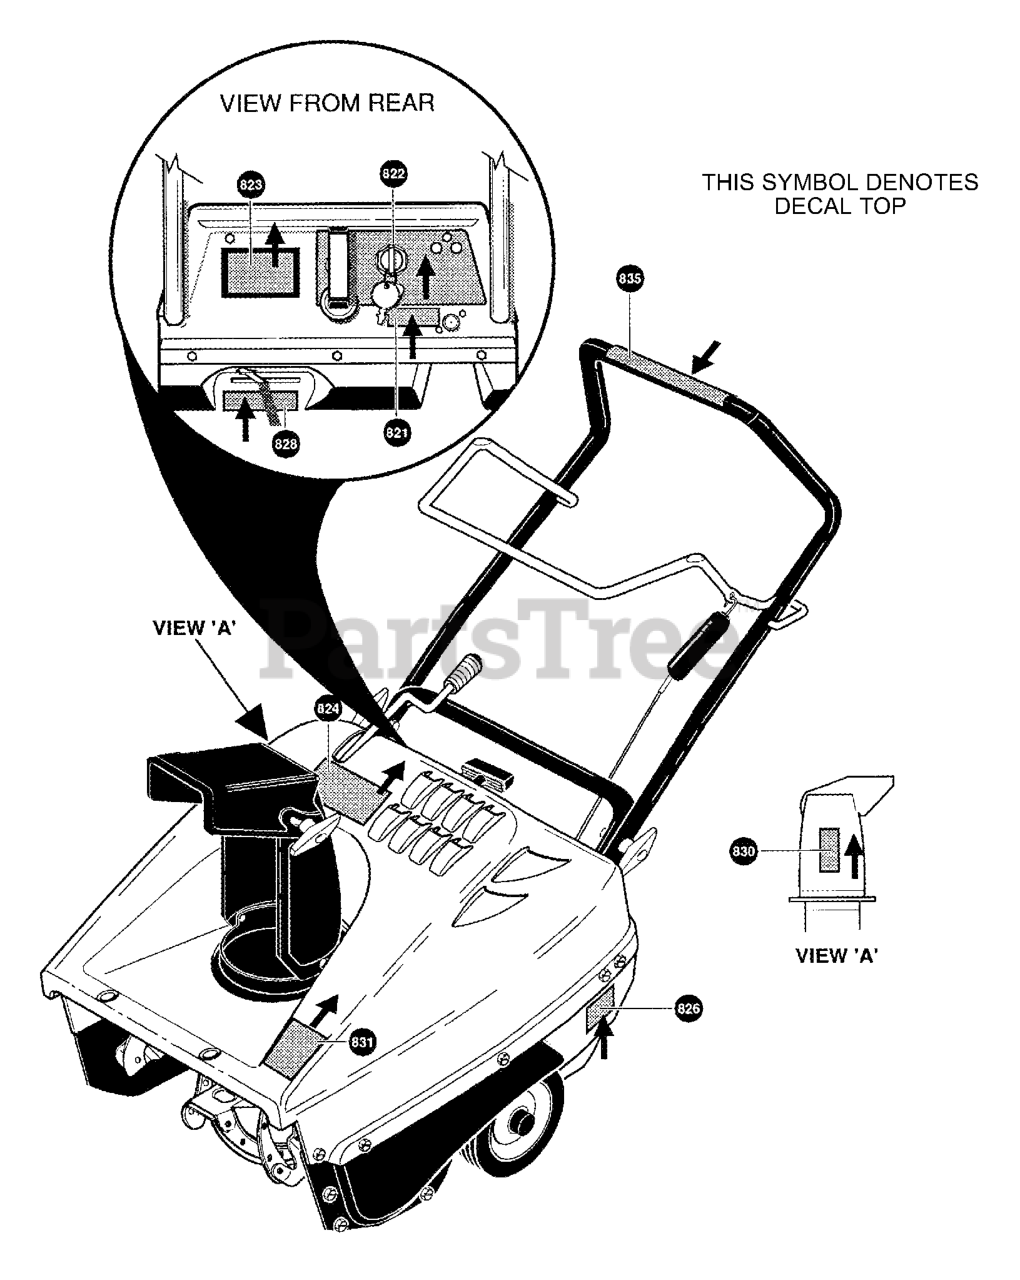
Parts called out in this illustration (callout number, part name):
820	DECAL, EPA 5HP, MASS
821	DECAL, ELECTRIC START FRE/ENG
822	DECAL, DASH
823	DECAL, SPARK PLUG ACCESS
824	DECAL, SNOW MAX
826	DECAL, MUFFLER HOT
828	DECAL, OFF-CHOKE-ON
830	DECAL, DANGER CHUTE -HAND
831	DECAL, DANGER AUGER -FOOT
835	DECAL, AUGER CONTROL BAR
